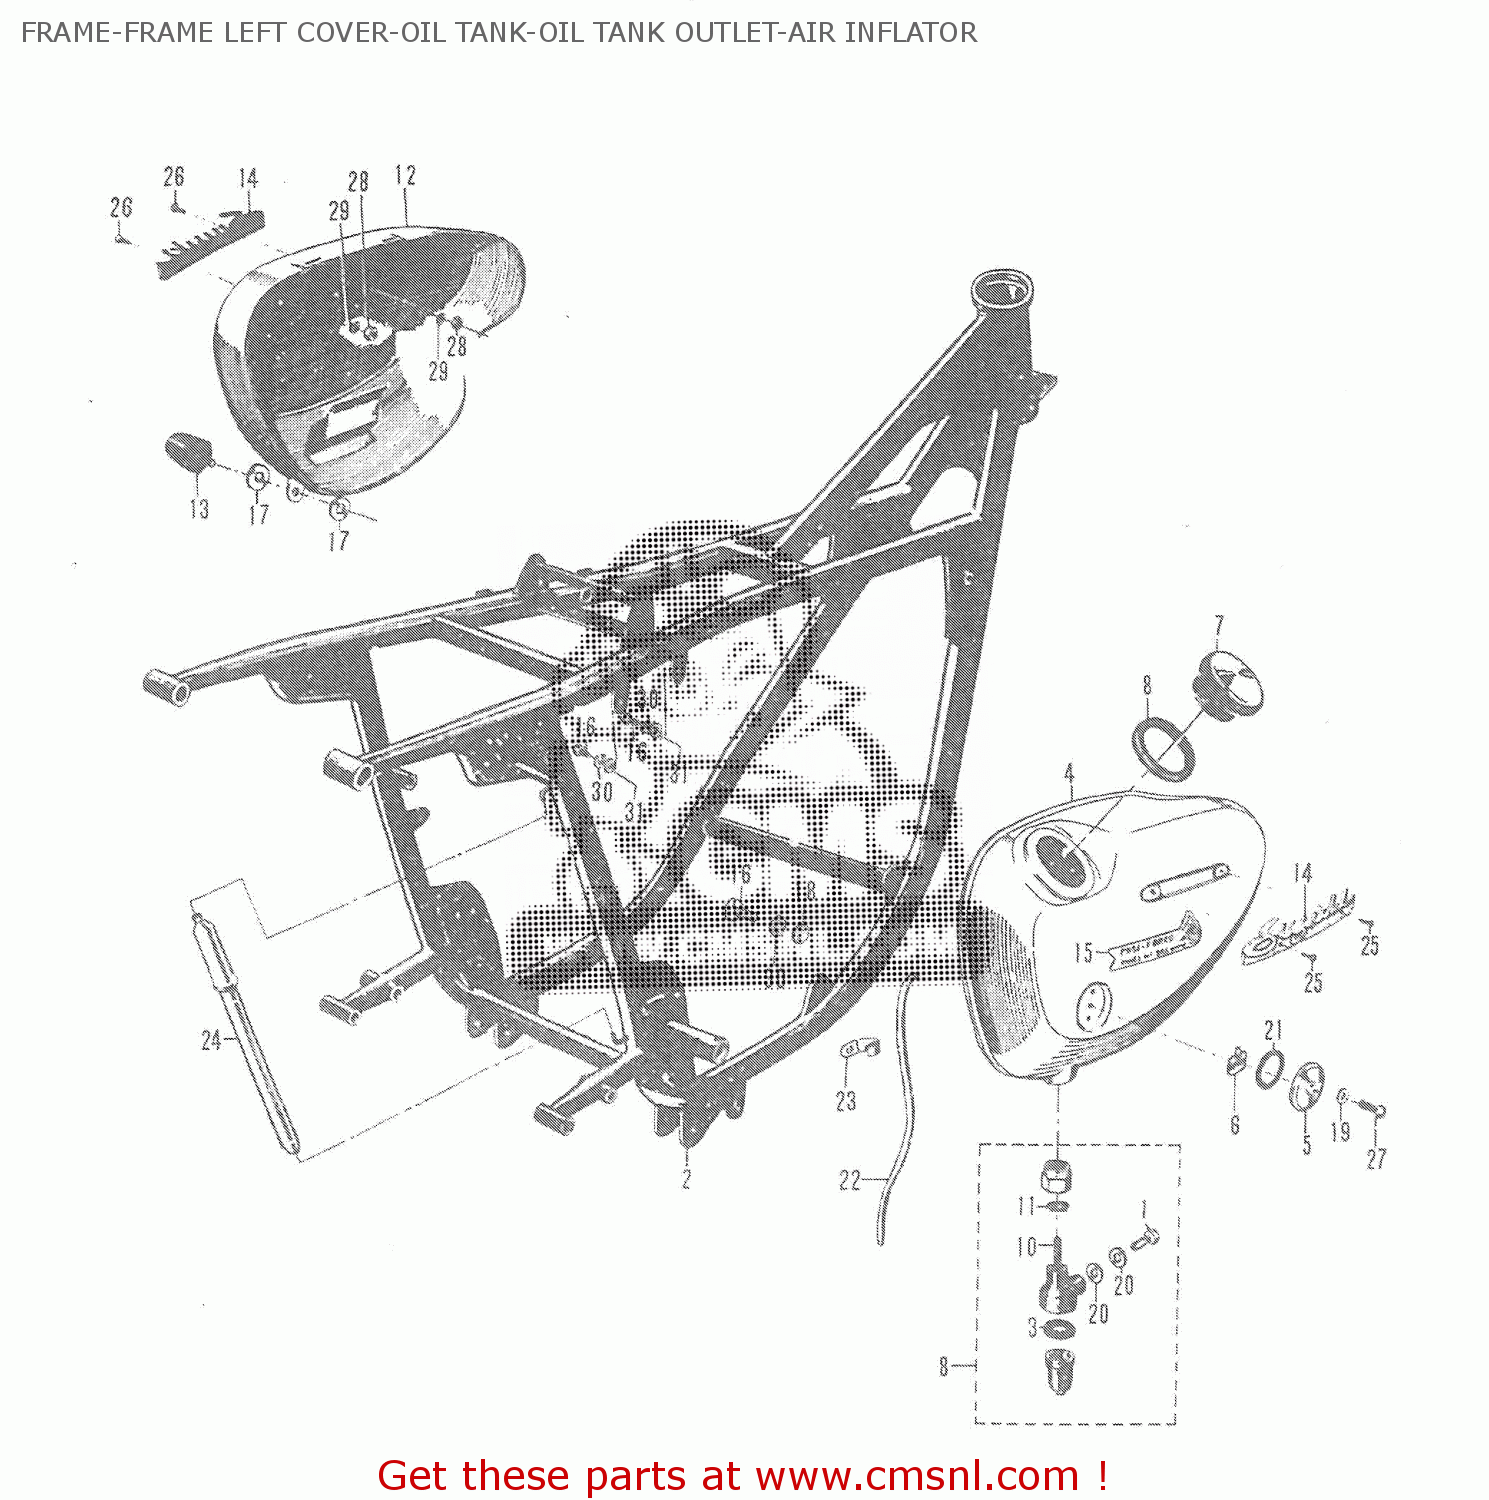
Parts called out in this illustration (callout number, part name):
1	OIL PUMP UNION BOLT
2	FRAME
3	GASKET,FUEL COCK STRAINER (NAS)
4	OIL TANK
5	LENS,INSPECTION
6	PLATE,OIL LEVEL INSPECTION
7	CAP,OIL TANK
8	GASKET,OIL TANK FILLER CAP (NAS)
9	OUTLET ASSY.OIL
10	UNIT,OIL FILTER
11	GASKET,OIL OUTLET JOINT (NAS)
12	FRAME LEFT COVER
13	FRAME COVER KNOB
14	EMBLEM
15	EMBLEM
16	BOLT
17	NUT
18	WASHER
19	GASKET(5X9.5X1) (NAS)
20	GASKET (NAS)
21	O RING(D:3,ID:23)
22	OIL BREATHER LINE
23	CLAMP
24	AIR INFLATOR
25	CROSS HEAD SCREW
26	CROSS HEAD SCREW
27	CROSS HEAD SCREW
28	HEXAGON NUT
29	LOCK WASHER
30	LOCK WASHER
31	FLAT WASHER
